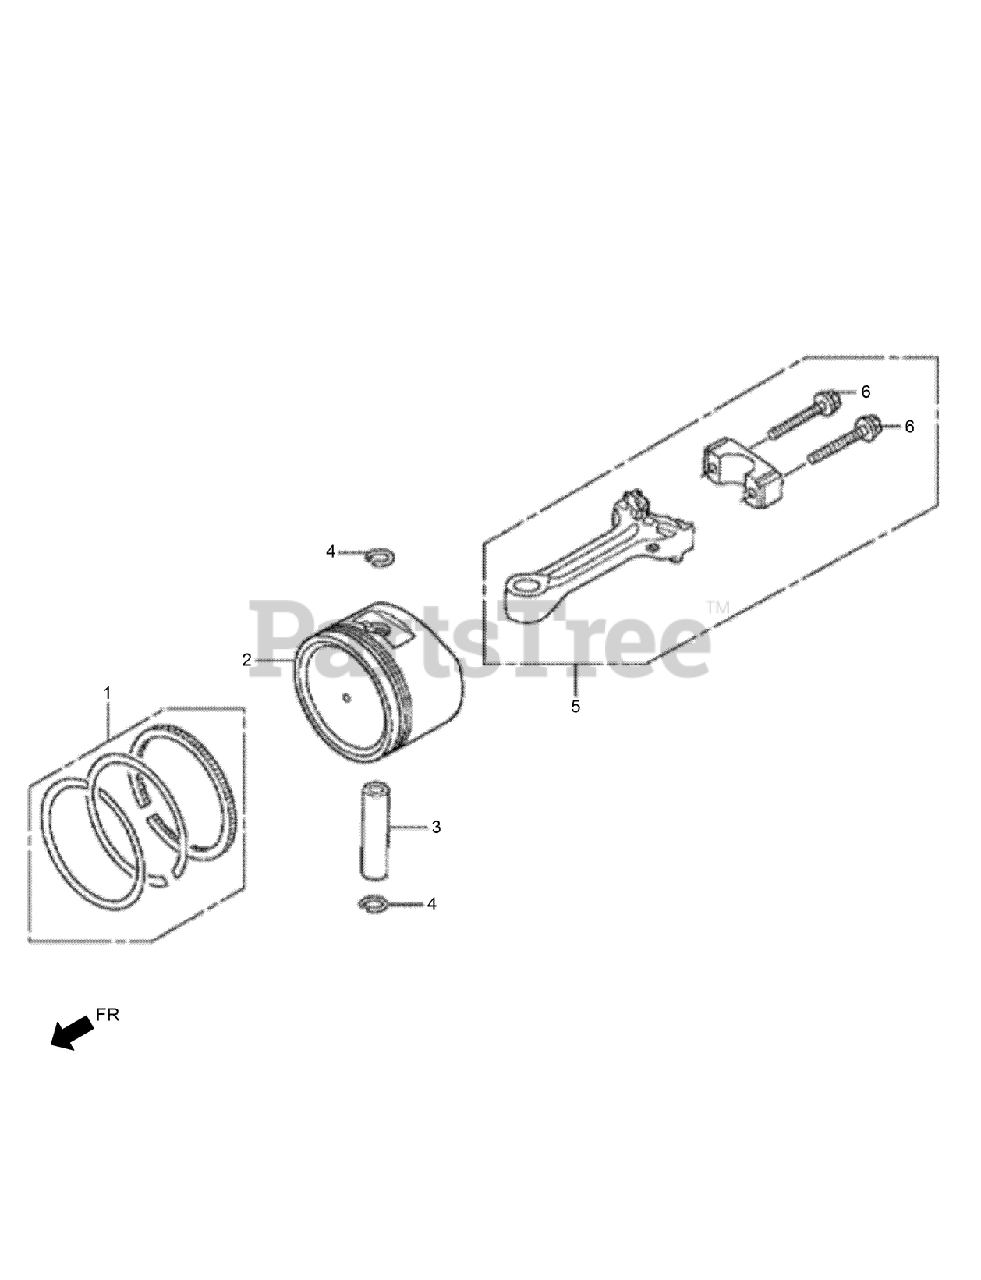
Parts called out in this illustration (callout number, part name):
1	RING SET-PISTON
2	PISTON
3	PIN-PISTON-10X33
4	CLIP-PISTON PIN-10MM
5	ROD ASM-CONNECTING
6	BOLT-CONNECTING ROD
